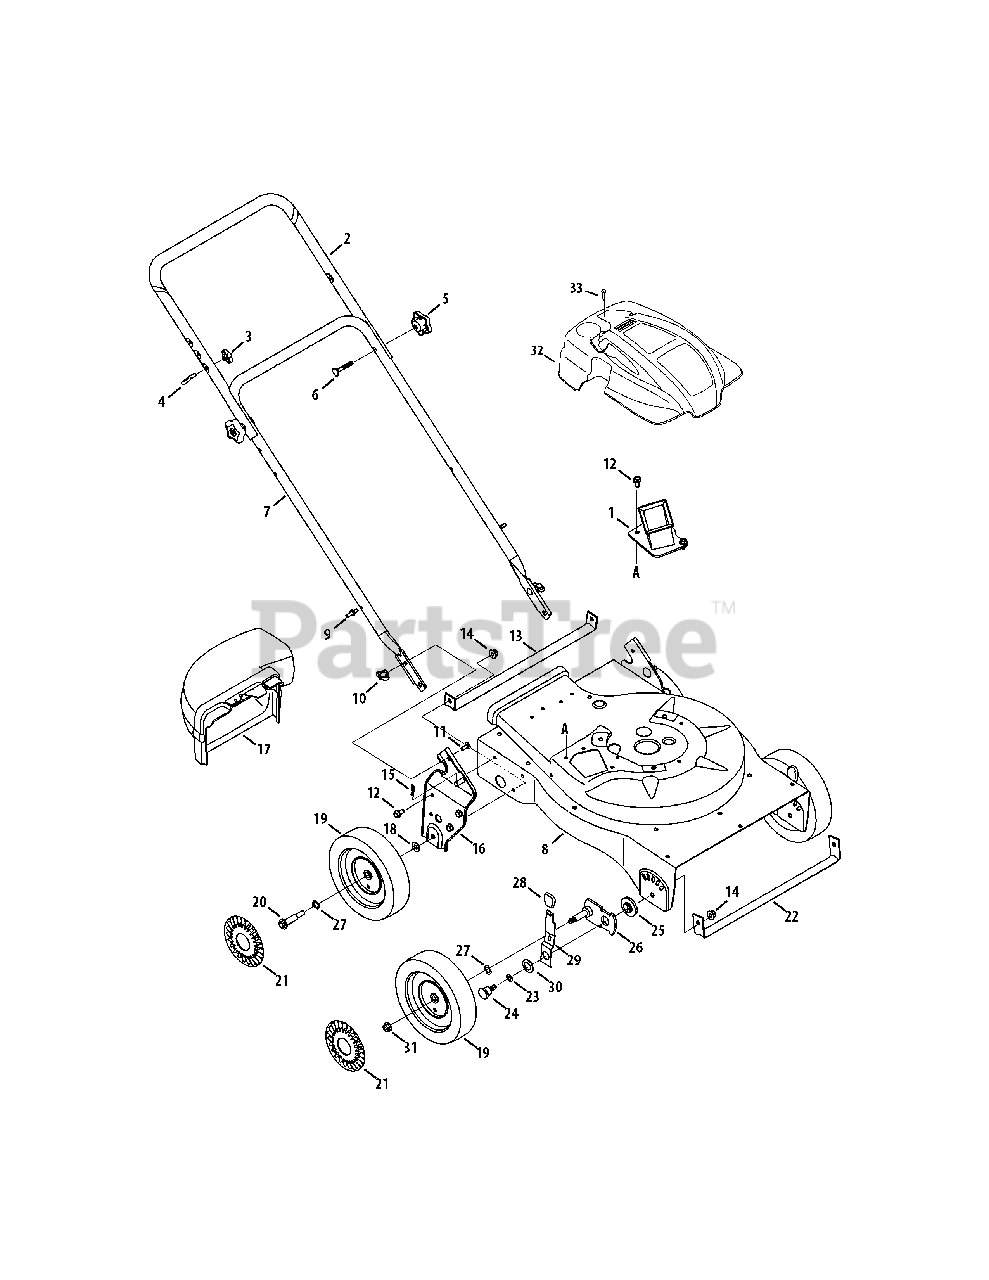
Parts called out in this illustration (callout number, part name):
1	Chipper Chute Assembly
2	Upper Handle
4	Eye Bolt
5	Star Knob, 5/16-18
6	Carriage Bolt
7	Lower Handle
8	Upper Housing
9	Studs
10	Wing Nut 1/4-20
11	Carriage Screw 1/4-20 x.75
12	Screw, 5/16-12 x.750
13	Rear Wheel Support Brace
14	Flange Lock Nut, 3/8-16
15	Cotter Pin
16	Handle Bracket Assy. LH
17	Blower Chute Assembly
18	Bell Washer.401 ID x.870 OD
19	Wheel, 8 x 1.8, Bar
20	Shoulder Screw 3/8-16
21	Hub Cap
22	Front Wheel Support Brace
23	Thrust Washer.375 ID x.70 OD
24	Shoulder Screw, .750 ID x .500
25	Height Adjustment Bearing
26	Pivot Arm Assembly
27	Wave Washer, .531 ID x .781 OD
28	Height Adjustment Knob
29	Spring Lever
30	Bell Washer.760 ID x.25OD
31	Flange Lock Nut, 3/8-16
32	Engine Shroud
33	Screw, #12-16 x 1.00
